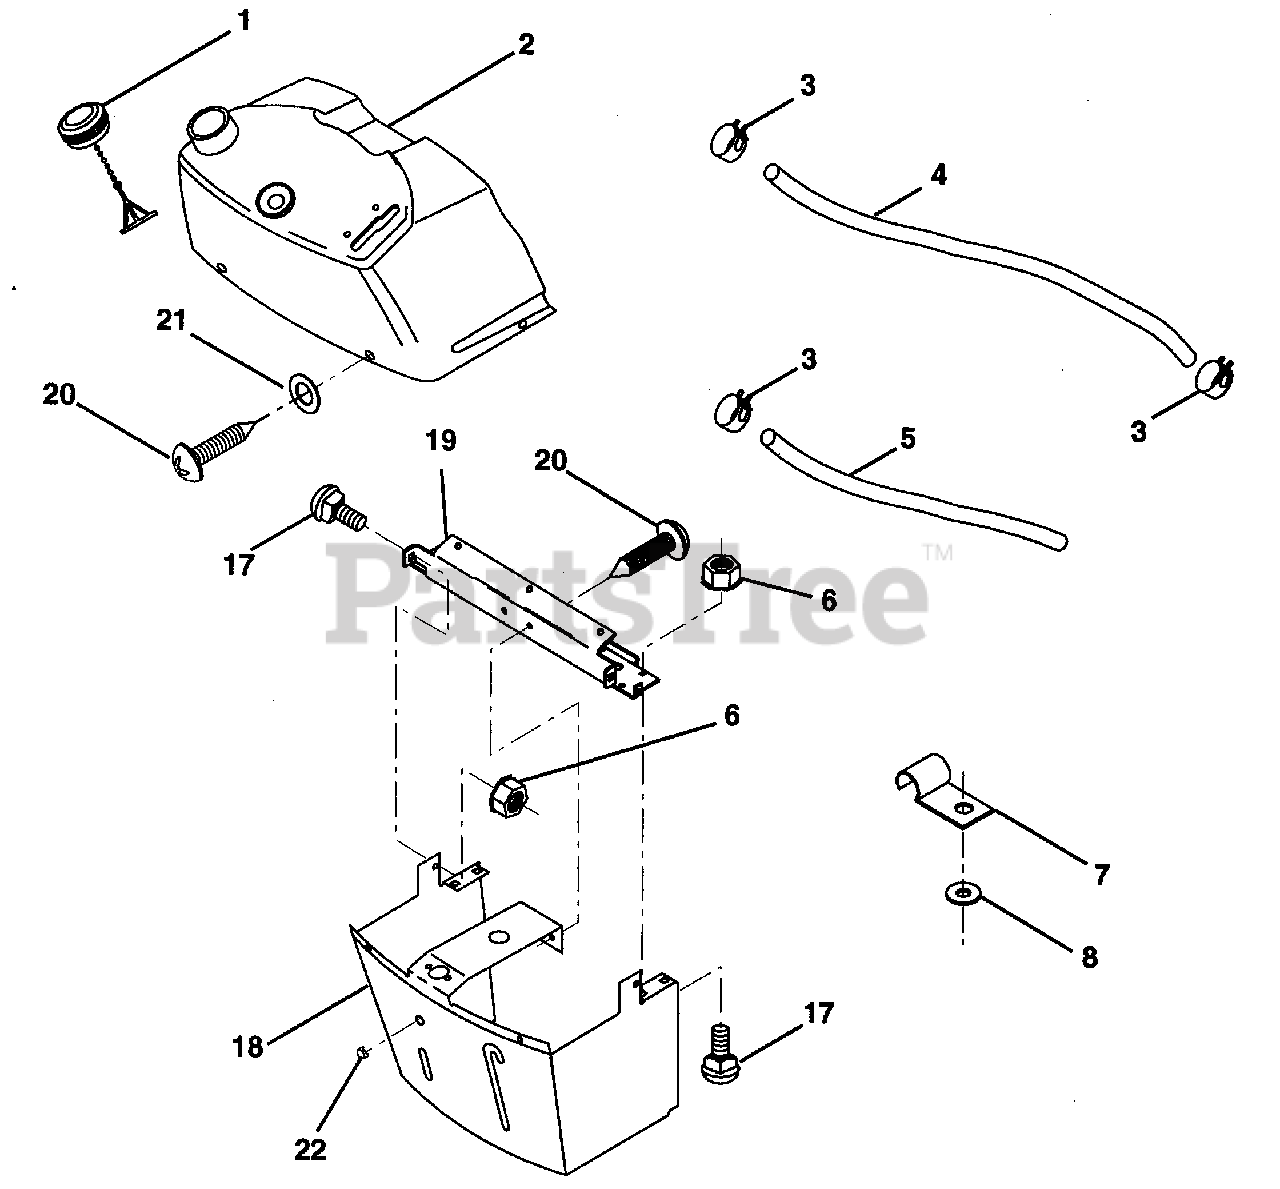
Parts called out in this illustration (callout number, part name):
1	Cap, Fuel (AYP part number)
2	Assembly, Dash & Fuel Tank (AYP part number)
3	Clamp, Hose (AYP part number)
4	Line, Fuel (AYP part number)
5	Line, Fuel (AYP part number)
6	Nut, Hex, Keps 1/4-20 (AYP part number)
7	Clip, Fuel Line (AYP part number)
8	Washer 9/32 x 3/4 x 16 Gauge (AYP part number)
17	Bolt, Carriage 1/4-20 x 1/2 Grade 5 (AYP part number)
18	Support Assembly, Dash (AYP part number)
19	Brace, Cross (AYP part number)
20	Screw, Self-Tapping 1/4-20 x 1/2
21	Washer 9/32 x 1/2 x 16 Gauge (AYP part number)
22	Plug, Dome (AYP part number)
